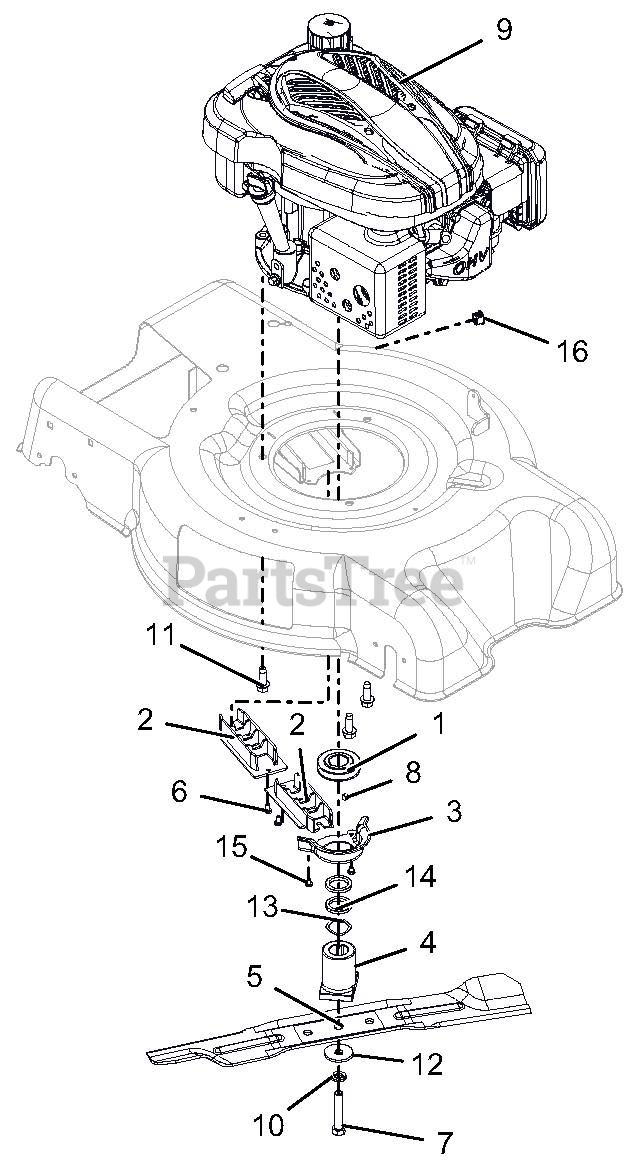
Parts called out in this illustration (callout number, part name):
1	PULLEY,MACHINED POWDER METAL
2	GUIDE, BELT INNER
3	GUIDE, BELT CRANK
4	ADAPTER, BLADE
5	BLADE, MOWER 21" HIGH LIFT
6	SCR-TAP 10-24X.375 PRE-COAT 80
7	@BLT-HEX .4375-20X2.25 GR8 YWZ
8	KEY-SQ .188X.188X.250
9	ENGINE, LONCIN 159CC VERT.
10	@WSHR-LK .44X.109 REG YWZC
11	@SCR-TAP .38-16X1.00 HWH TR YZ
12	WSHR-FL-STL .4375X1.50X.125 YZ
13	WASHER - WAVE 1.09X1.37X.016
14	SPCR, 1.00 X 1.375 X .179
15	SCR-TAP 10-24X.25 CRSLPH TR YZ
16	PLUG, DOME-BLACK, .625 DIA
